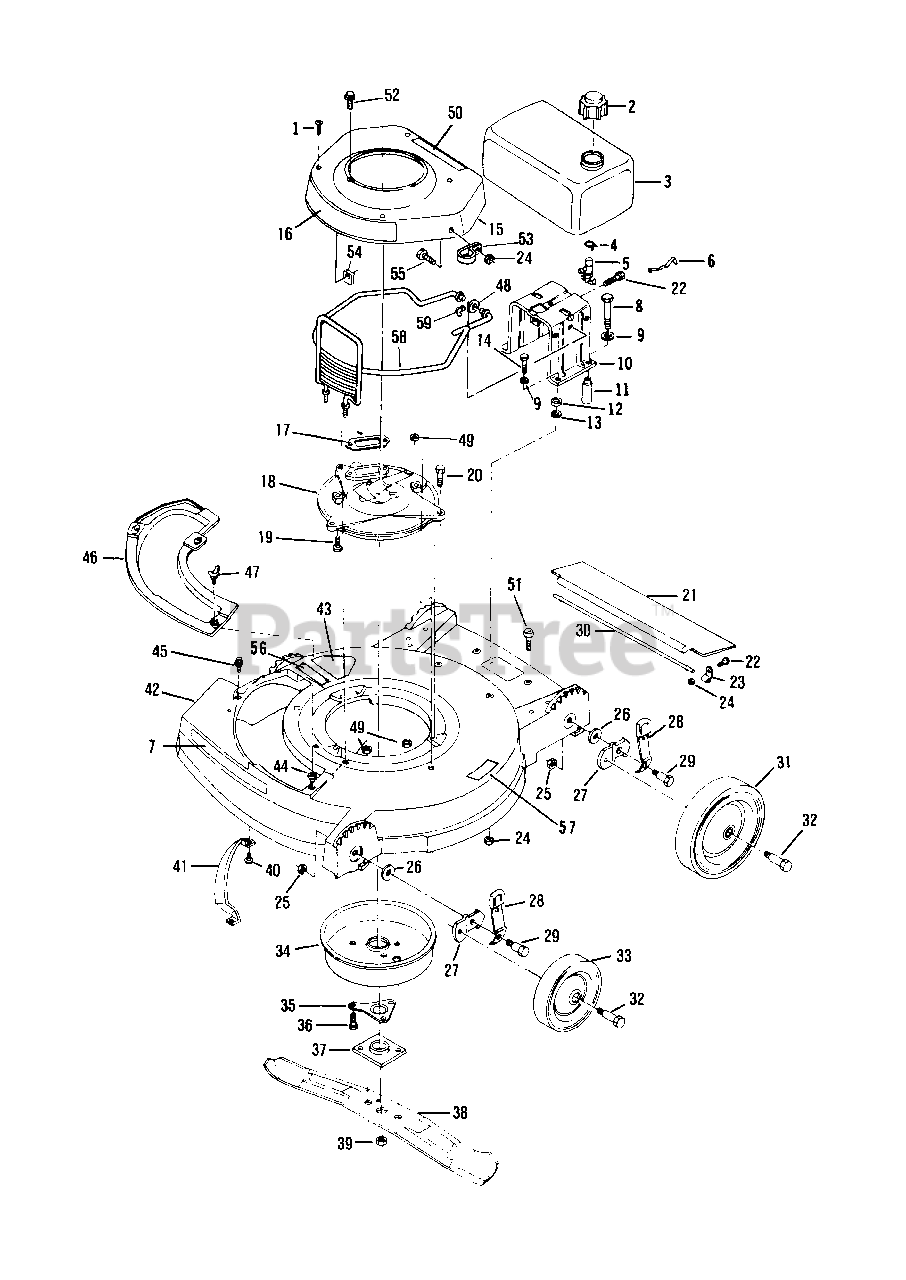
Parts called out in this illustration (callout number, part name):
1	Screw
2	Fuel Cap
3	Fuel Tank
4	Clamp
5	Shut-Off Valve and Screen
6	Spring-Fuel Tank Mounting
7	Decal-Headliner
8	Screw
9	Washer-Tank Mounting
10	Bracket-Fuel Tank
11	Spacer-Tank Mounting
12	Grommet-Tank Mounting
13	Washer-Tank Mounting
14	Bolt-Tank Mounting
15	Shroud
16	Applique
17	Gasket-Exhaust
18	Plate-Muffler
19	Screw-Muffler Plate to Block
20	Screw-Muffler Plate to Housing
21	Shield-Trailing
22	Screw
23	Clamp
24	Nut
25	Nut
26	Washer
27	Bracket-Wheel Height Adjust
28	Knob and Spring Assembly
29	Bolt-Shoulder
30	Rod-Trailing Shield
31	Wheel-Rear-8"
32	Bolt-Wheel
33	Wheel-Front-6"
34	Muffler Cover Assembly
35	Support-Crankshaft
36	Screw-Muffler to Muffler Plate
37	Collar and Plate Assembly
38	Blade-21"
39	Nut-Blade
40	Screw
41	Toe Bar
42	Housing Assembly
43	Decal-Blade Contact Warning
44	Grommet
45	Screw-Sems-Plate Mounting
46	Cover-Chute
47	Wing Screw
48	Spring-Washer
49	Nut-Guard and Engine Mounting Plate
50	Decal-Fuel Mixture
51	Screw
52	Screw-Starter
53	Clamp
54	Retainer
55	Screw
56	Decal
57	Decal
58	Guard-Engine Assembly
59	Hair Pin
